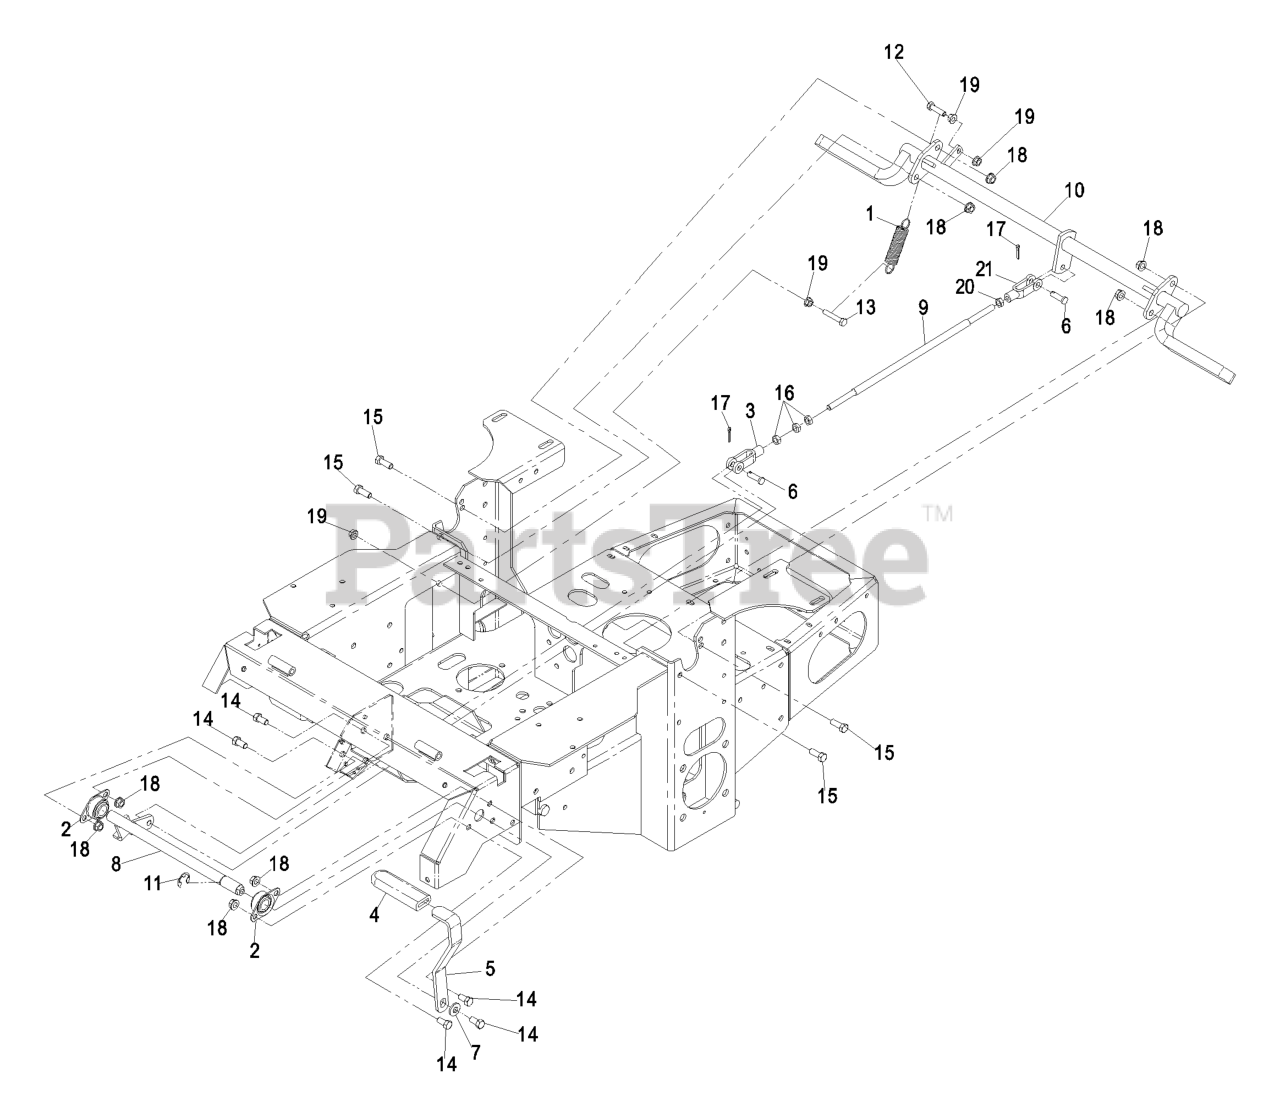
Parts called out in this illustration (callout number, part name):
1	SPRING-IDLER
2	BEARING-FLANGE, SIDE
3	YOKE-LINKAGE, BRAKE
4	GRIP-LEVER
5	ASM,BRAKE HANDLE W/ GRIP
6	PIN-CLEVIS
7	WASHER-BELLEVILLE
8	SHAFT-BRAKE, PARKING
9	LINKAGE, BRAKE (PLTD)
12	SCREW-HH
13	SCREW-HH
14	SCREW-HH
15	SCREW-HH
16	NUT-HEX
17	PIN-COTTER
18	NUT-HHF, WHIZ
20	NUT-HEX, LH
21	YOKE, LH YZ
